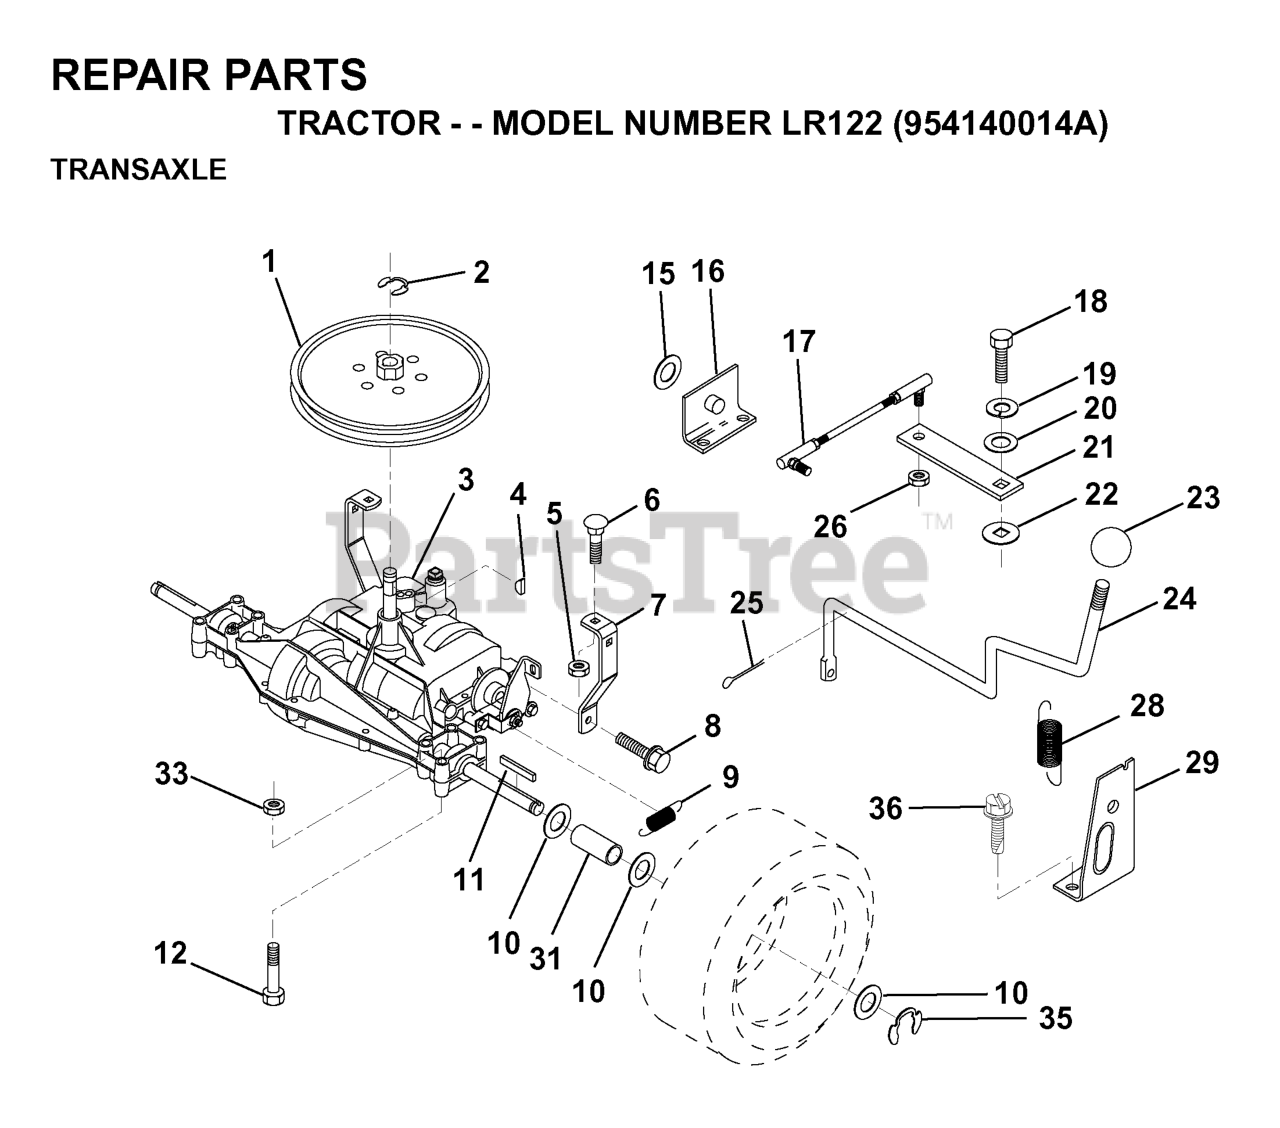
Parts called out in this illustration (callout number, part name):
11	Assembly, Kit, Shim, .625 Shaft
12	Bearing, Flange
14	Key, Woodruff, No. 9
22	Assembly, Kit, Clutch Keys
24	Shaft, Intermediate
29	Gear, Spur, 37 Teeth
33	Gear, Spur, 19 Teeth
34	Spacer, 1.133 X 1.50 X .375
43	Assembly, Kit, Shim, .750 Shaft
45	Gear, Spur, 12 Teeth
52	Washer, Neoprene
61	Housing, Lower
